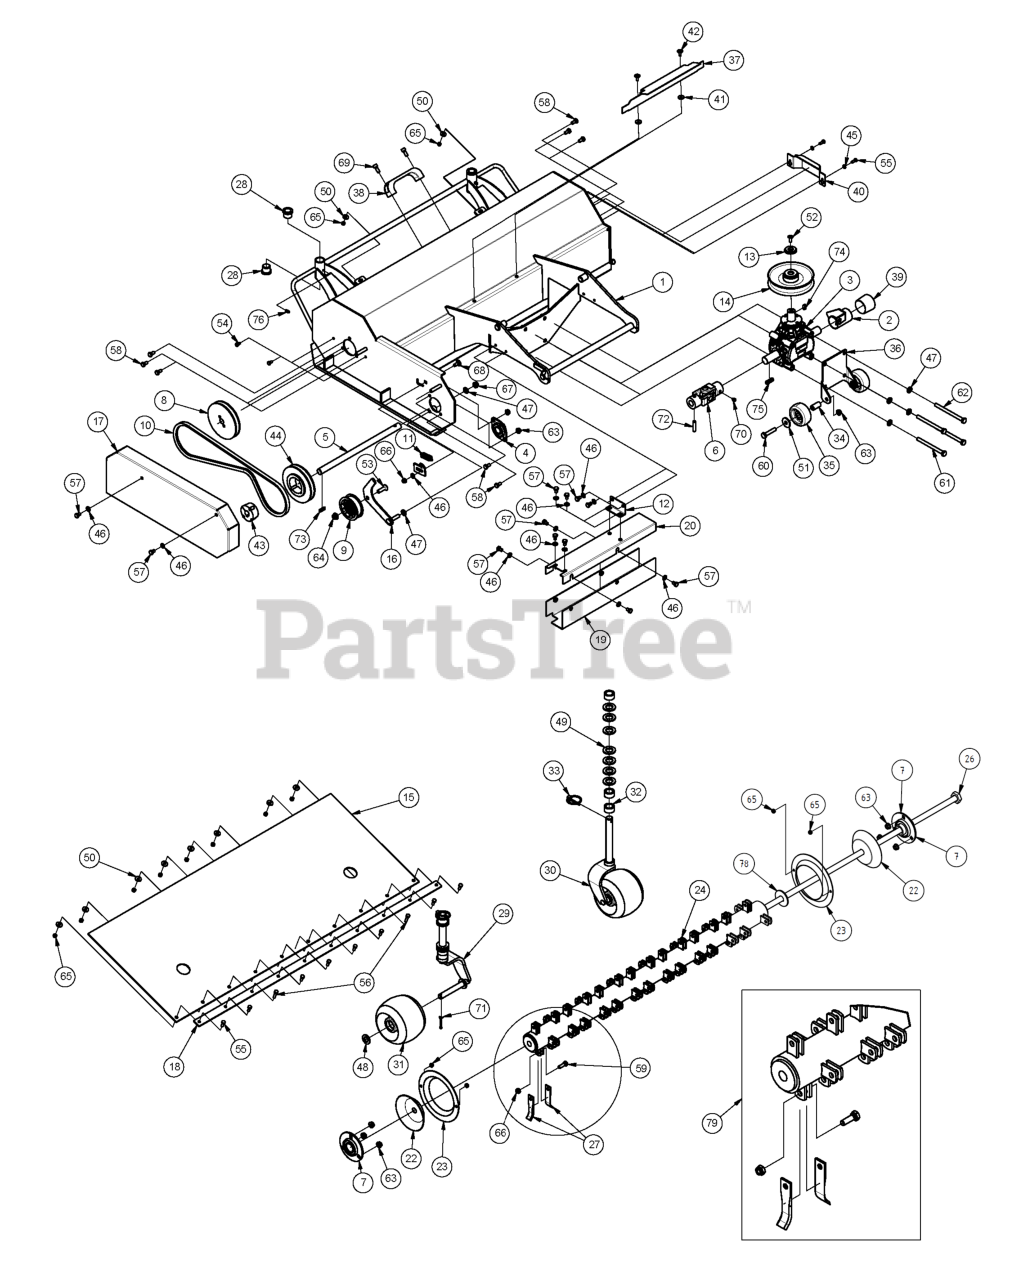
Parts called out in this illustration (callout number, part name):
2	GUARD
6	LINK
11	SPRING
13	WASHER
25	SPACER
27	BLADE
28	BUSHING
31	DECK ROLLER, FRONT
33	PIN
34	COLLAR
35	SUPPORT WHEEL
39	DUST COVER
40	HAND GUARD
42	SCREW
63	NUT LOCKING
65	NUT
66	NUT
67	NUT
68	SCREW
69	SOCKET
70	SCREW
76	NIPPLE
